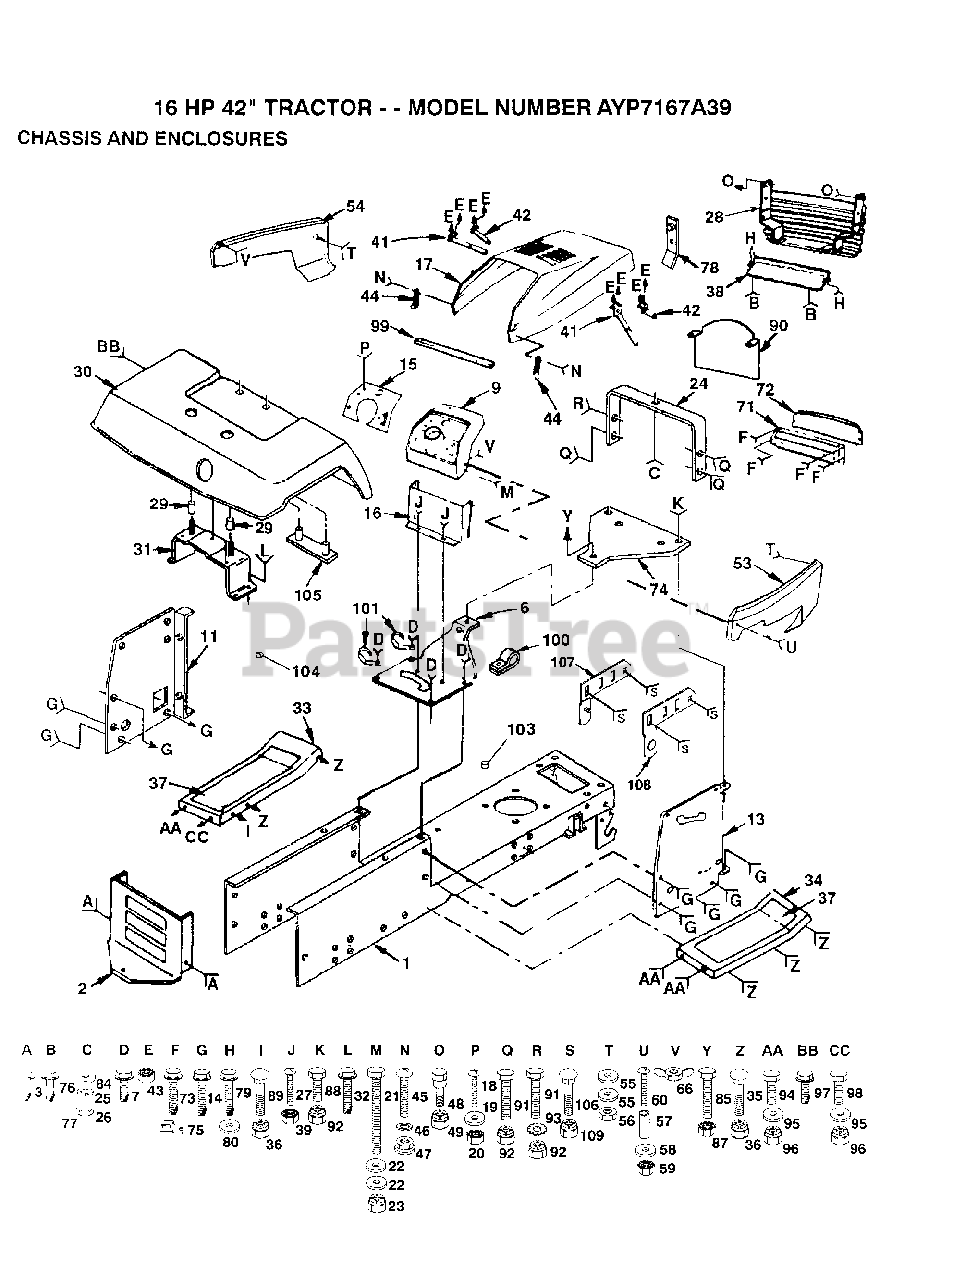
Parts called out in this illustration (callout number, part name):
3	SCREW
6	SADDLE.DANA.6SP
7	SCREW LT
11	PANEL.DASH.LH
14	SCREW
15	PLATE.SLKSCR.DASH
16	DASH ASSY LT
18	SCREW
19	WASHER
22	WASHER
24	SUPPORT ASS'Y
25	LOCKWASHER
27	SCREW
29	NUT-PUSH YT
30	FENDER
31	BRKT.ASM.FENDER
32	SCREW
35	BOLT
37	FOOTREST PAD
43	NUT
44	HOOD LATCH T
45	SCREW
46	LOCKWASHER
47	WELDNUT
55	WASHER PM
57	SPACER LT
58	WASHER
60	SCREW
72	LENS LT
75	"""J"" FASTENER LT"
76	SCREW
77	WASHER
79	SCREW HEX CRT
80	WASHER
84	WASHER PM
85	BOLT
90	"BAFFLE,HOOD"
93	LOCKWASHER
95	WASHER
97	SCREW LT
99	FOAM-STRIP LT
100	CLIP T
101	CLIP T
103	SNAP BUSHING T
106	BOLT
107	PIVOT BRKT LH
108	PIVOT BRKT RH
109	NUT
